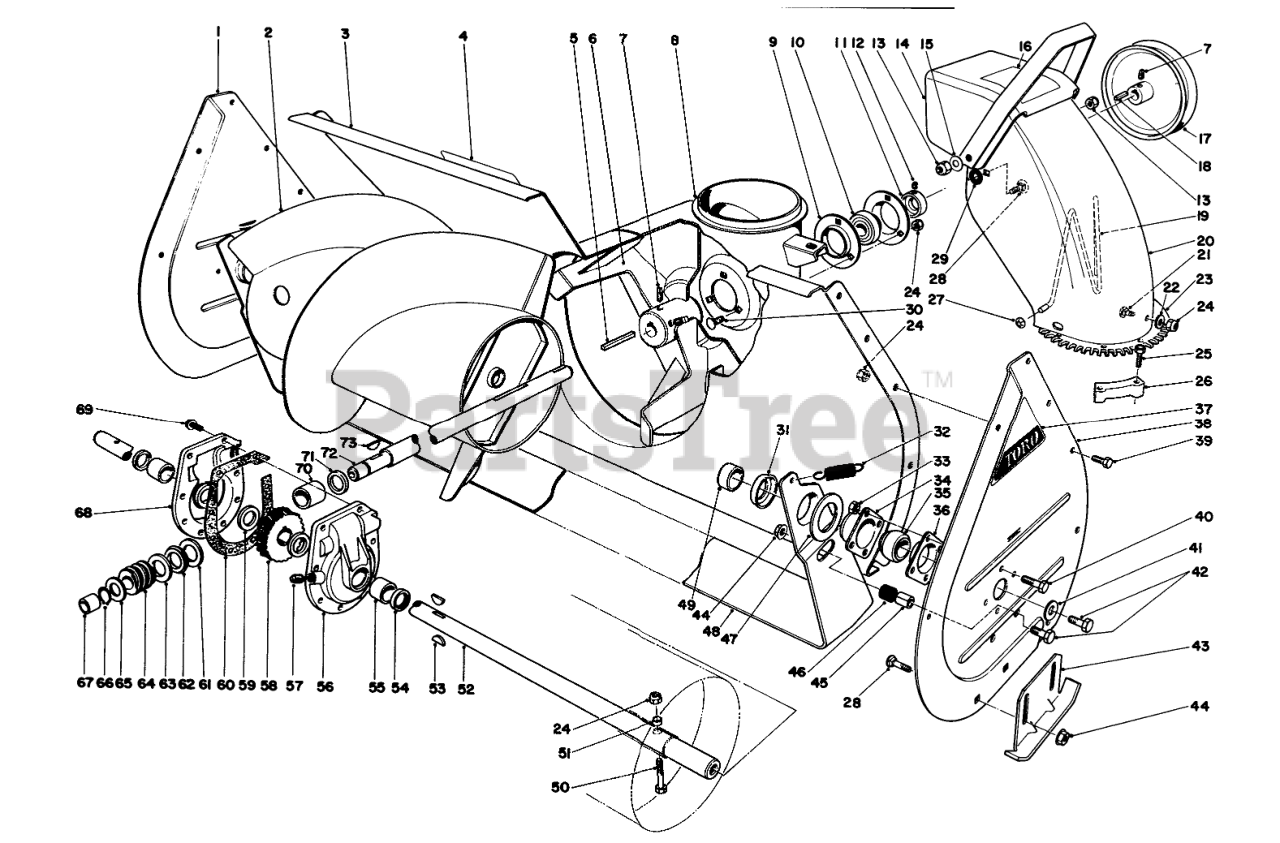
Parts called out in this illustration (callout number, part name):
1	RH AUGER SIDE PLT R
2	RH AUGER ASM - 32"
3	AUGER HSG WA 32" R
4	Decal-Warning
6	IMPELLER ASM
7	Set Screw
8	CHUTE RING
9	BRG FLANGE
10	BALL BRG W/COLLAR
11	EXT LOCKING COLLAR
12	SCREW-HSH
13	NUT-LOCK, CONE
14	Deflector (Incl. Ref. #16)
15	WASHER-BELLEVILLE
16	Decal-Danger
17	1/2 X 9.5 DIA PULLEY
18	SQUARE KEY
19	WIRE-CHUTE
20	Upper Chute
21	SCREW-CARR
22	WASHER-PLAIN
23	Screw
24	NUT-LOCK, NI
25	SCREW-SPECIAL
26	RETAINER-CHUTE
27	NUT-PUSH
28	SCREW-CARR
29	WASHER-RUBBER
30	BOLT-CARR
31	Positioner-Scraper
32	SPRING-TENSION
33	NUT-LOCK, CONE
34	BEARING-FLANGE, FRONT
35	BEARING
36	BEARING-FLANGE, REAR
37	AUGER SIDE PLT DECAL
38	LH AUGER SIDE PLT R
39	SCREW-HH
40	SCREW-HH
41	WASHER
42	SCREW-HH
43	AUGER SKID WA R
44	NUT-HF
45	SCRAPER STOP SPACER
46	SCRAPER STOP CUSHION
47	SCRAPER BLADE SPACER
48	SCRAPER BLADE 32" R
49	AUGER SPACER
50	Auger Bolt
51	SPACER-HUB, AUGER
52	32 AUGER SHAFT
53	KEY-WOODRUFF
54	SEAL-OIL
55	BUSHING
56	Gear Case L.H. (Incl. Ref. #54-55)
57	PLUG-PIPE, SQH
58	GEAR-WORM, 27T
59	WASHER-THRUST
60	GASKET-CASE, GEAR
61	WASHER-THRUST
62	BEARING-THRUST
63	THRUST-WASHER
65	WASHER-THRUST
66	Ring-Snap
67	BUSHING
68	Gear Case R.H.(Incl. Ref. #54-55)
69	Thread Form Screw
70	BUSHING-SPECIAL
71	RING-QUAD
72	SHAFT-IMPELLER
73	KEY-WOODRUFF
